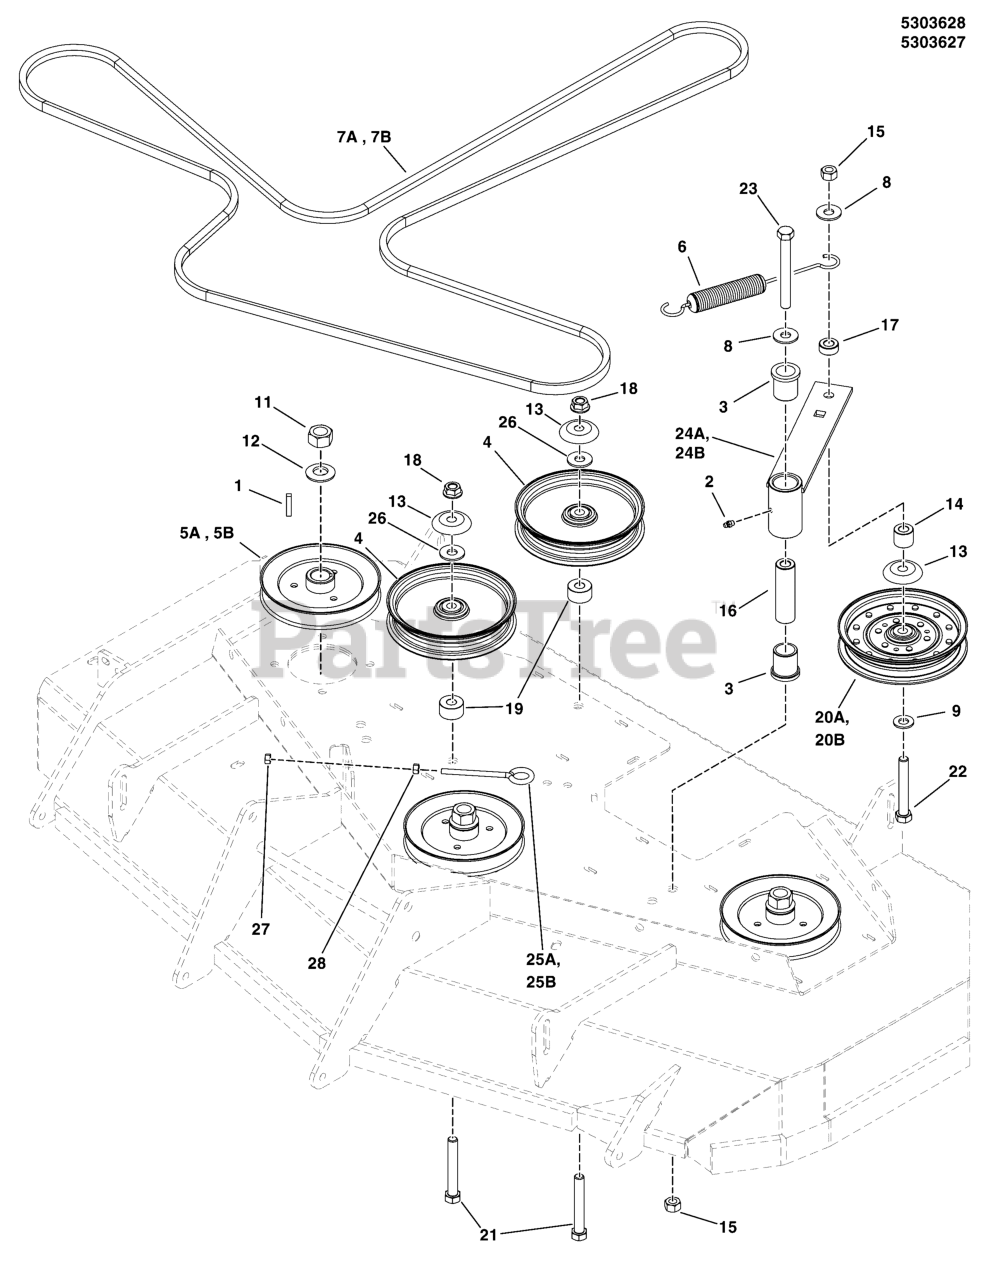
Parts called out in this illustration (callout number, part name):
1	KEY, 1/4" SQ. X 1-1/4
2	GREASE FITTING, 1/4-28 Straight
3	BUSHING, FLANGE
5A	PULLEY, 5.540OB X .985ID, SINGLE B-SEC
5B	PULLEY, 5.926OB X .985ID, SINGLE B-SEC
6	SPRING-EXT, 1.25OD X 9.3LG X .142WR, BLK
7A	BELT, 5V, 147.40"EL, LRG ARAMID,WRPD, RC
7B	BELT, 5V, 163.40EL, LG ARAMID, WRPD, RC
8	WASHER, 1/2" USSZ
9	WASHER, 1/2 SAE
11	NUT, 3/4-16 Hex
12	WASHER, 3/4 BELLEVILLE CL/ZC
13	SHIELD, PULLEY BEARING, CZ
14	SPACER, .52 X 1.00 X .88, PM, CZ
15	NUT, 1/2-13 Hex Side Lock
16	SPACER, .52 x 1.00 x 3.50
17	SPACER, .52 X 1.00 X .44, CZ
18	NUT, Hex Flange, Nylock, 1/2-13
19	SPACER, .52 X 1.25 X .70, PM, CZ
21	BOLT, 1/2-13 X 2-3/4 GD5 CZ
22	BOLT, 1/2-13 X 3-1/2, HEX HD, GD5, CZ (SV)
23	BOLT, 1/2-13 X 4-1/2" GD5 YZ
24A	WELD, IDLER ARM - BLK
24B	WELD, IDLER ARM - BLK
25A	EYE BOLT, 3/8-16 X 5, 2.88THRD, 1EYE, CZ
25B	EYE BOLT, 3/8-16 X 6, 3THRD, 1EYE, CZ
26	WASHER, 1/2 SAE
27	NUT, 3/8 - 16 HEX NYLOCK FLANGE
28	NUT, 3/8-16 HEX JAM
